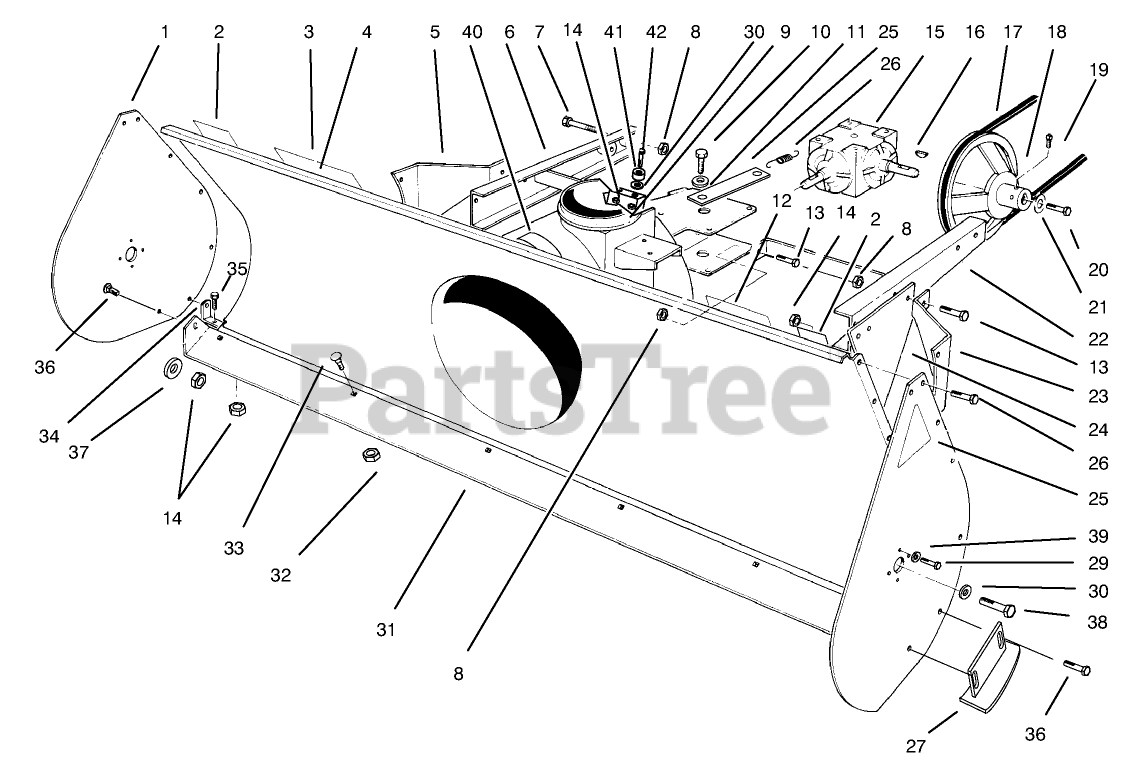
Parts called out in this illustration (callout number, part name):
1	Plate-Side
2	DECAL-DANGER
3	DECAL-WARNING
4	ASM - AUGER HSG W/DECALS
5	RH EXTENSION PLT R
6	RH EXT BAR WA R
7	SCREW-HH
8	NUT-LOCK, NI
9	CHUTE RING
10	SCREW-HH
11	WASHER-LOCK, INTERNAL
12	DECAL - WARNING
13	SCREW-HH
14	NUT-LOCK, NI
15	GEARBOX
16	KEY-WOODRUFF
17	V-BELT
18	DRIVE PULLEY
19	SCREW-SET, SQH
20	BOLT 60183
21	WASHER-FLAT
22	LH EXT BAR WA R
23	LH EXTENSION PLT R
24	SKID MTG PLT R
25	BRACKET - SPRING
25	DECAL
26	IDLER EXT SPRING
26	SCREW-HH
27	Skid
29	SCREW-HH
30	WASHER
31	Blade-Scraper
32	NUT-LOCK, NI
33	SCREW-CARR
34	BLADE SUPPORT BRKT R
35	SCREW-HH
36	BOLT-CARR
37	WASHER-PLAIN
38	SCREW-HH, LOCK
39	WASHER-FLAT
40	DECAL-PROLINE
41	BUMPER
42	SCREW-HH
